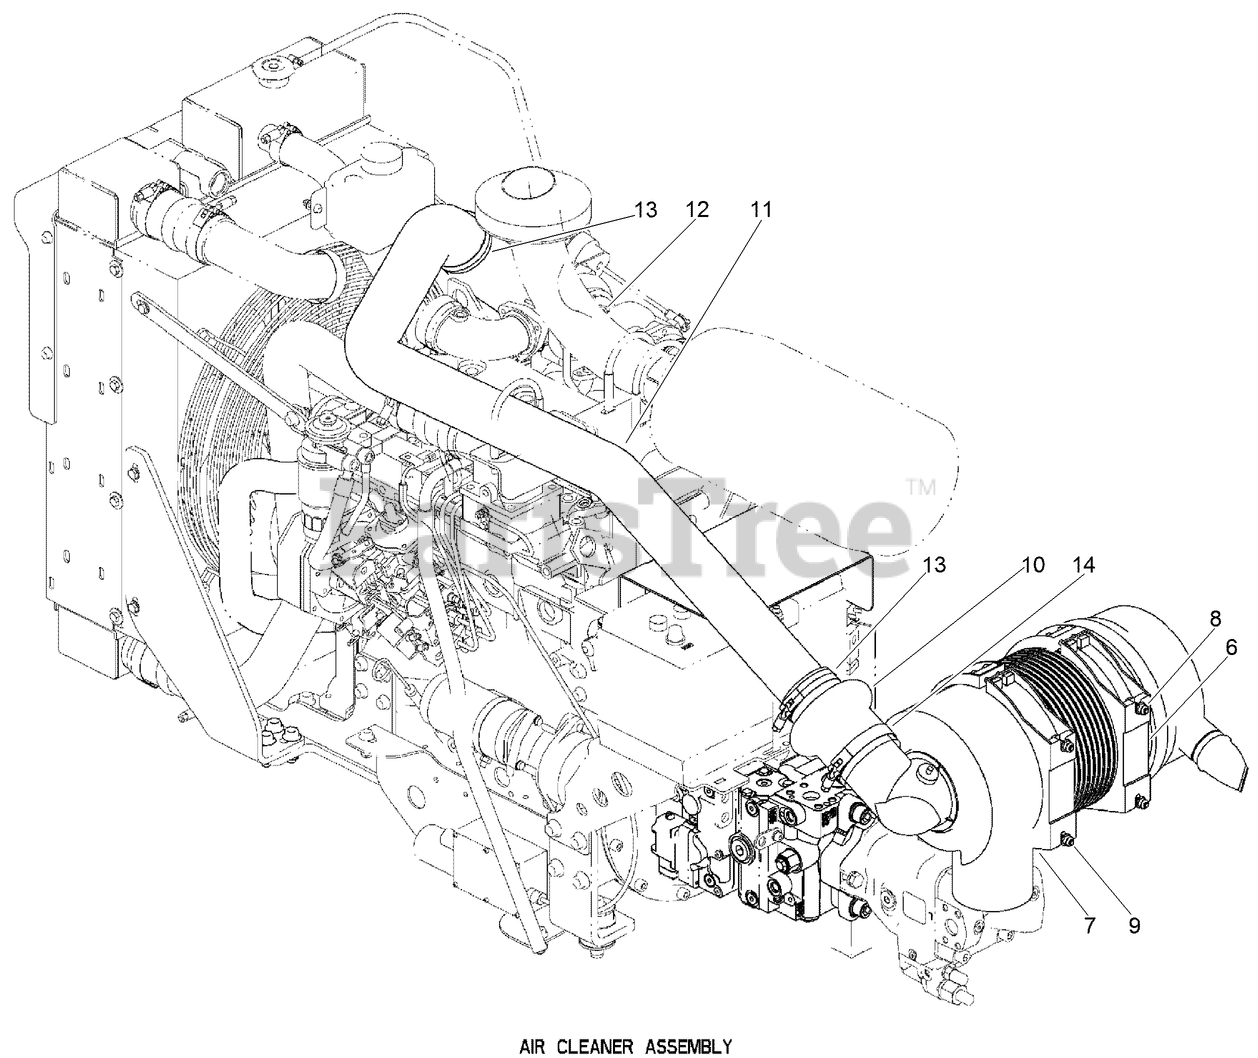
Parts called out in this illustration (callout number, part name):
6	MOUNT-Air Cleaner
7	ASM-Air Cleaner
8	SCREW-HHF
9	NUT-TORQUE, PREVAILING
10	REDUCER-HOSE
11	TUBE - Air Intake
12	ELBOW - 90 Deg Intake 3.00 x 90
13	CLAMP - TBolt, Spring Load Min 3.38 Max 3.69
14	CLAMP - TBolt, Min 95.3 Max 103.2
